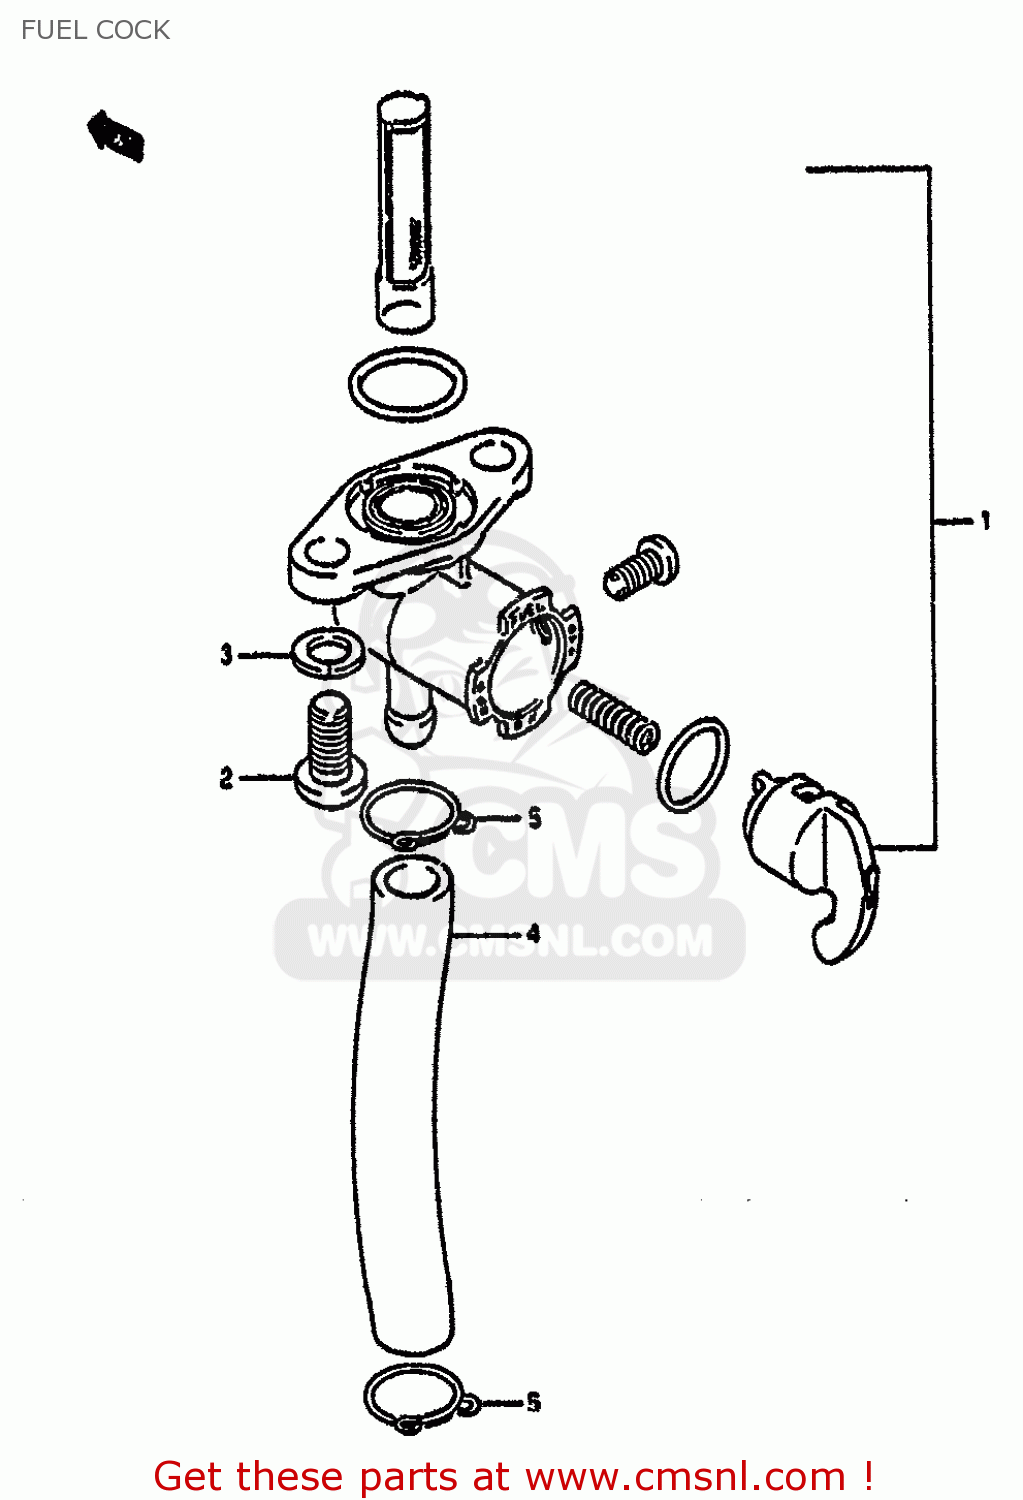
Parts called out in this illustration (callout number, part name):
1	COCK ASSEMBLY,FUEL
2	SCREW
3	WASHER,LOCK
4	HOSE
5	CLIP
